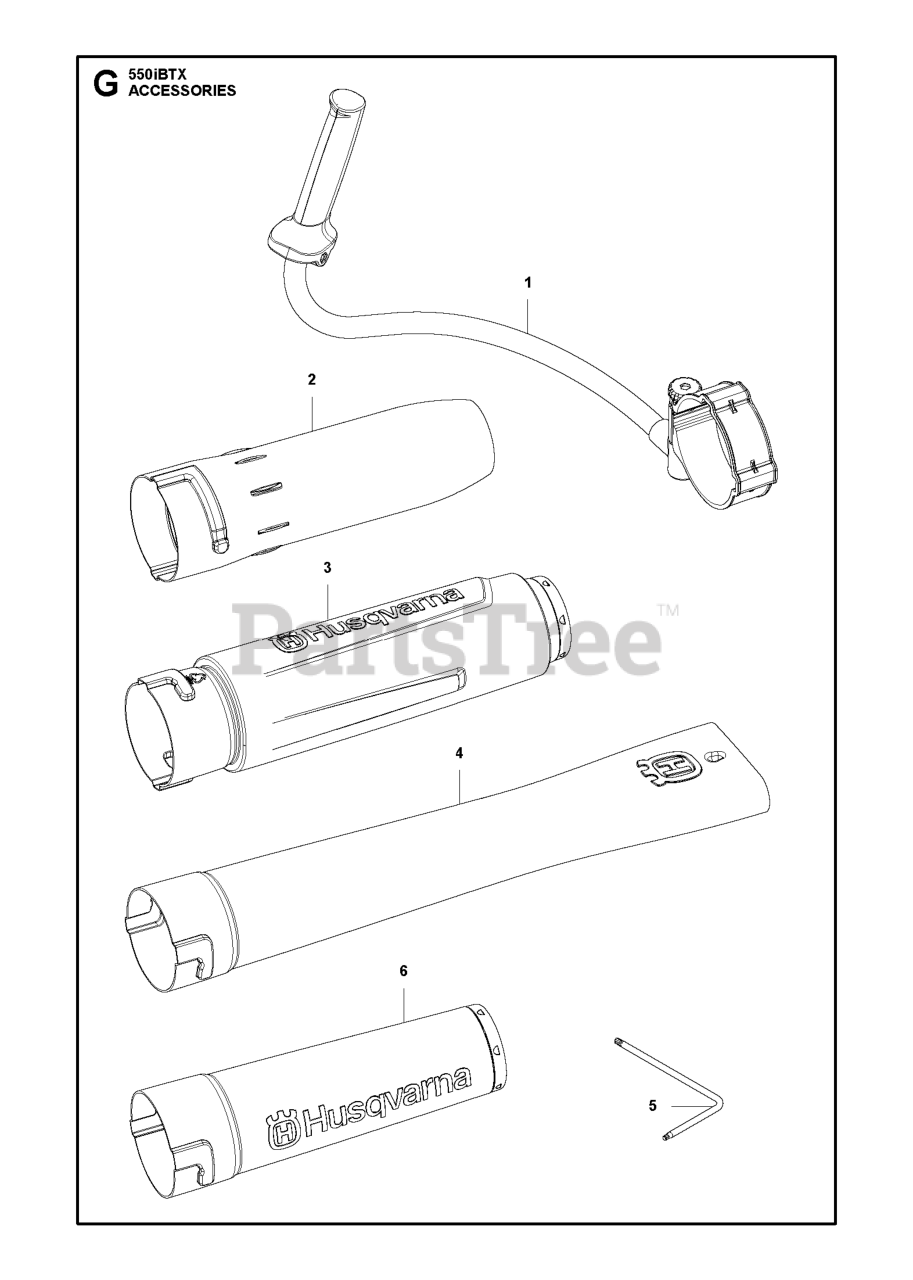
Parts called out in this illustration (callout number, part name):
1	HANDLEBAR ASSY
3	TUBE ASSY NOZZLE SILENCER
4	BLOWER NOZZLE FOR 320IB
